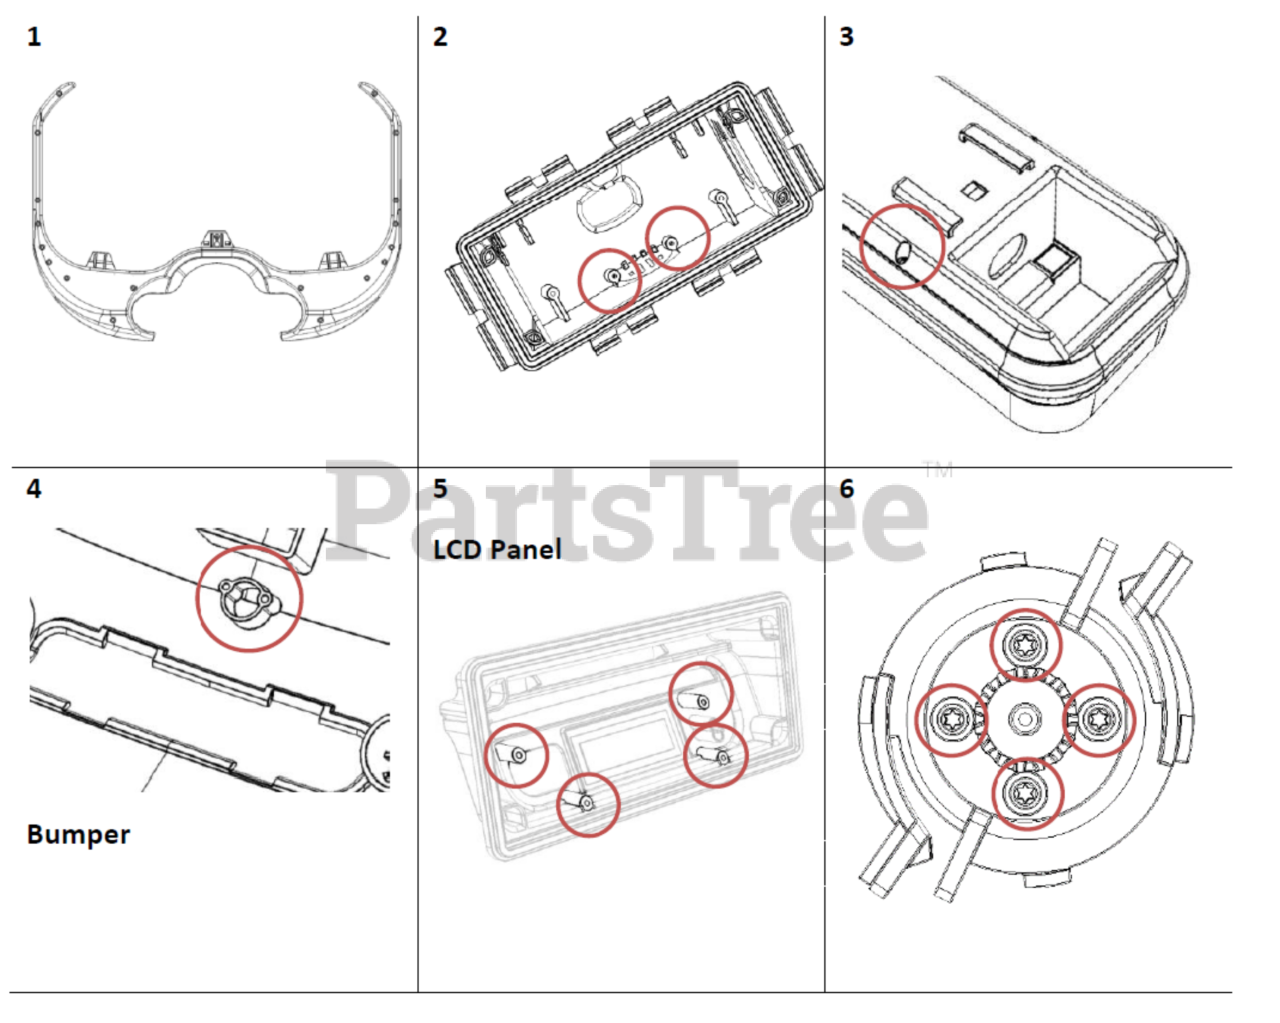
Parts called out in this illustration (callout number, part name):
1	SCREW-KA40 x 20 WN
2	Torx WN1451 K40 L12
3	EJOT WN 1452 K30 L
4	EJOT WN 1452 K30 L
5	EJOT WN 1452 K30 L
6	TOREXS M5 10MM-COL
